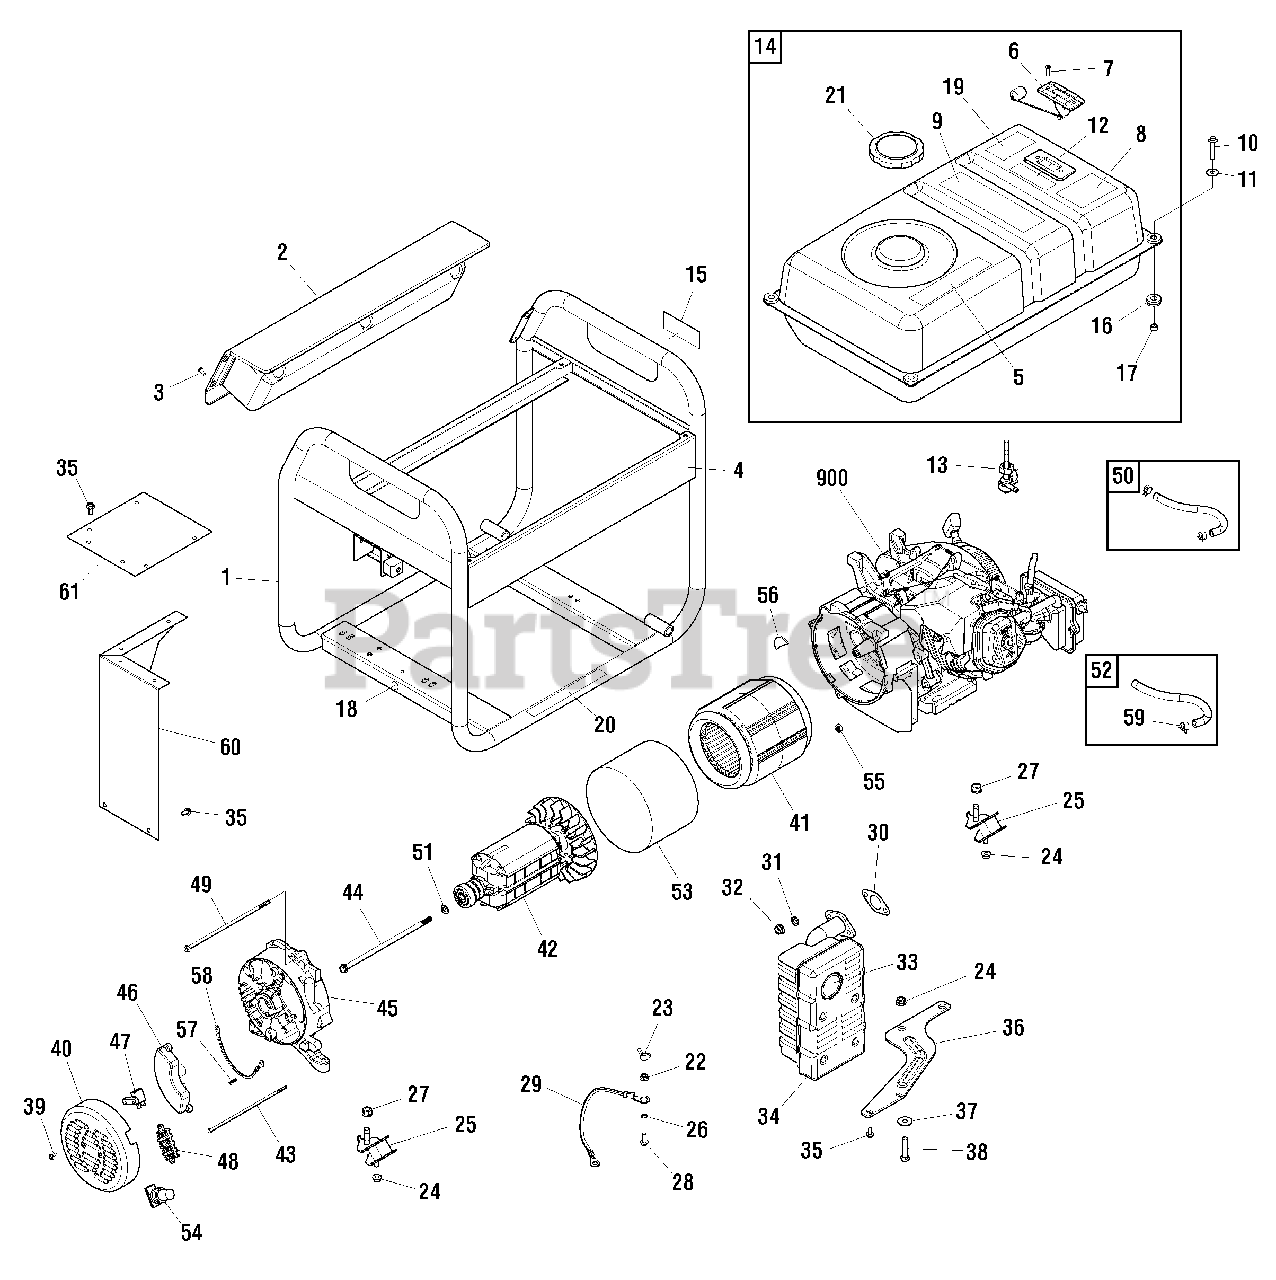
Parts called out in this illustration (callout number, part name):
2	PANEL-CONTROL
22	* NUT, Flange Lock, M6
24	* NUT, Flange Lock, M8
25	MOUNT-VIBRATION
26	* WASHER, Shakeproof, Ext, M6
27	* NUT, Flange Lock, M10
28	* SCREW, Flange, M6 x 16
30	GASKET
31	* WASHER, Lock, M8
32	* NUT, Hex, M8-1.25
35	* SCREW, Flange, M6 x 12
36	BRACKET-MUFFLER
37	* WASHER, Flat, M8
38	HHCS-M8-1.25 x 40
45	CARRIER-BEARING
46	VOLTAGE REGULATOR
50	KIT-FUEL HOSE (cut to fit)
52	HOSE-VAPOR (cut to fit)
900	** ENGINE
